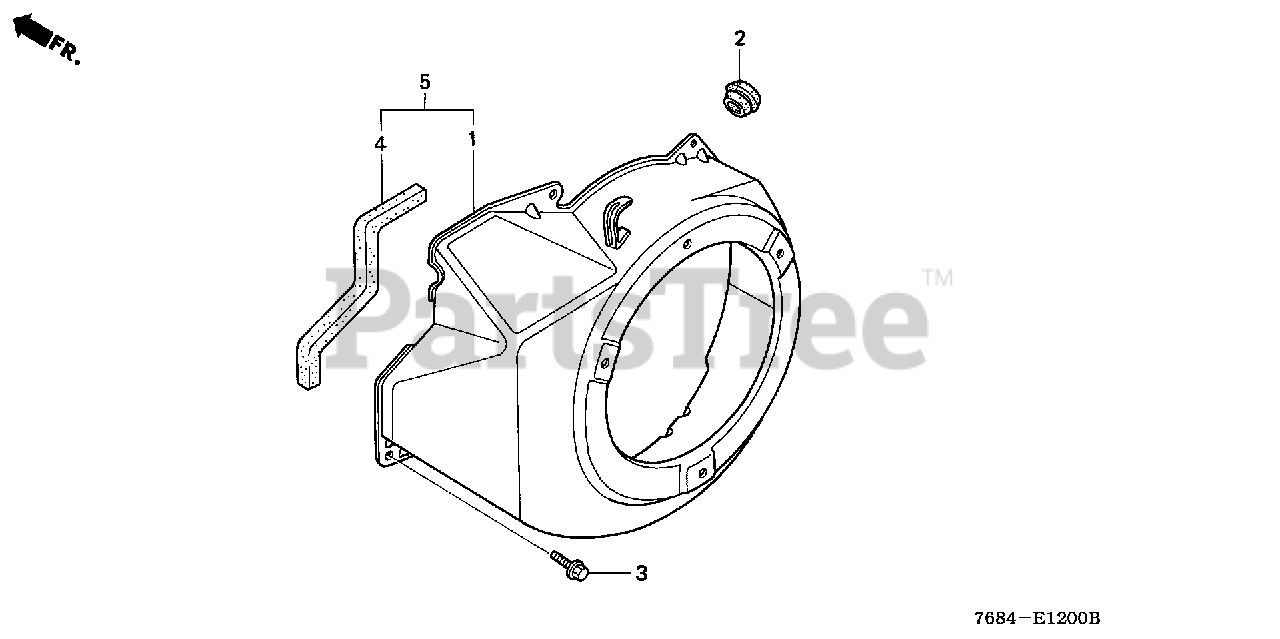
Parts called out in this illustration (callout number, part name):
2	GROMMET, DRAIN HOLE
3	BOLT, FLANGE (6X12) (CT200)
4	SEAL, RECOIL
5	COVER, FAN *R8* (BRIGHT RED)
5	COVER, FAN *R280* (POWER RED)
